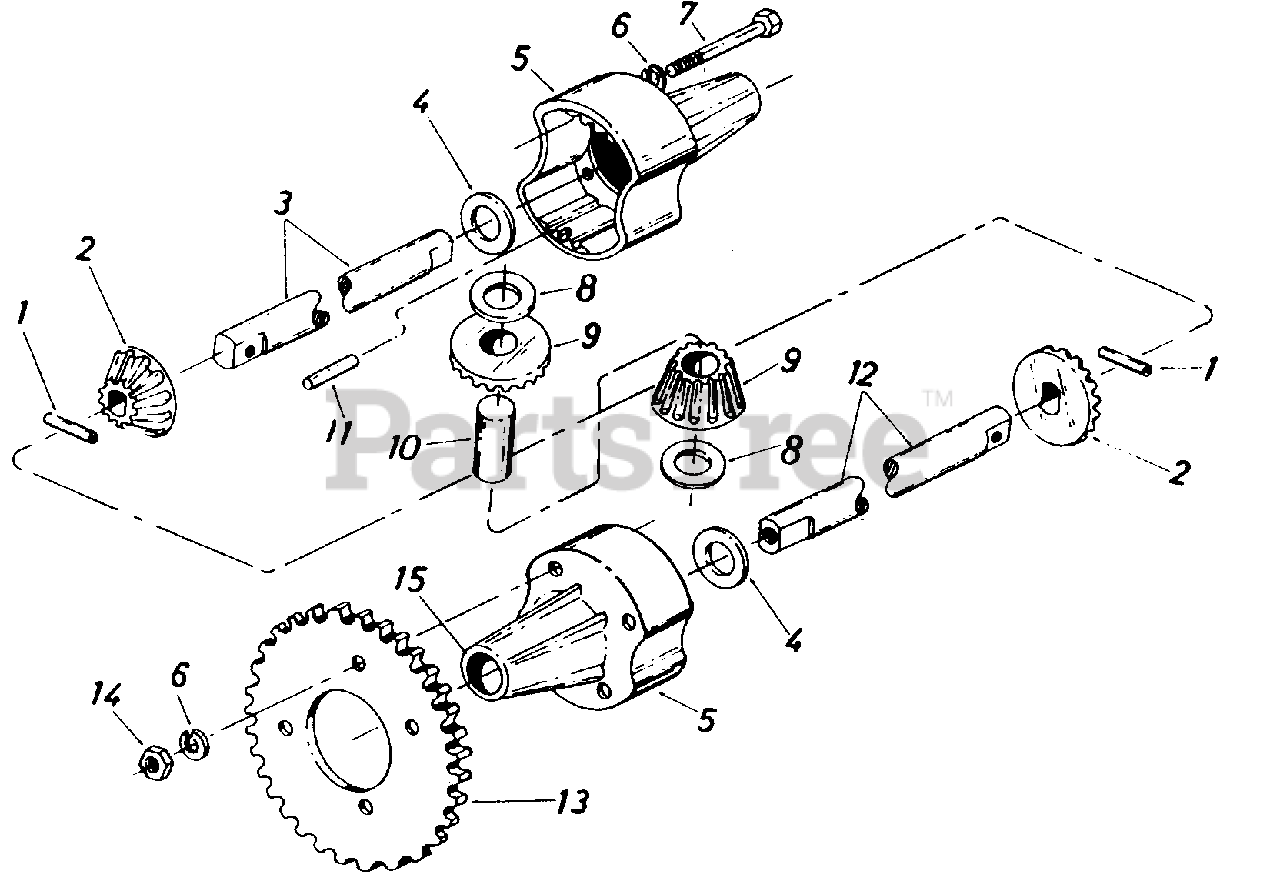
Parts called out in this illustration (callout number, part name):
1	Spring Pin Spiral 3/16" Dia. x 1.0" Lg.
2	Gear-Double"D" Hole
3	Shaft (Long)-15.11" Lg.
4	Fl-Wash. .76" I.D. x 1.49"
5	Housing Half
6	L-Wash. 5/16" I.D.
7	Hex Bolt 5/16-24 x 4" Lg.
8	Fl-Wash. .64" I.D. x .24"
9	Gear-Round Hole
10	Drive Pin
11	Dowel Pin 3/16" Dia. x .62"
12	Shaft (Short) 7.58" Lg.
13	Sprocket-48 Teeth
14	Hex Cent. L-Nut 5/16-24 Thd.
15	Flange Bearing
